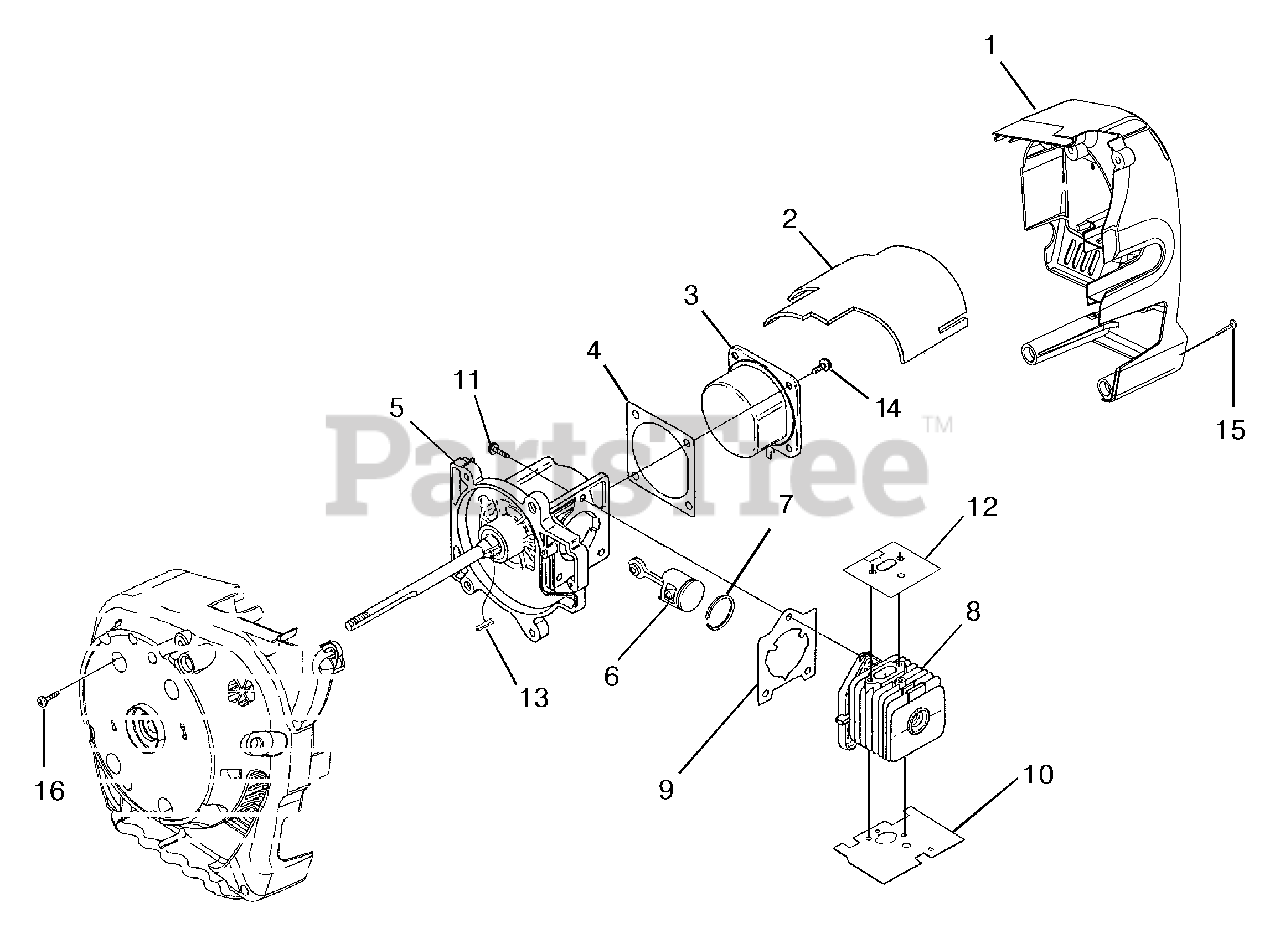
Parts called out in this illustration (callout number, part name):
1	Shroud
2	Heat Shield, Muffler
3	Crankcase Cover
4	Gasket, C/Case
5	Short Block (Svc)(30cc)
5	Short Block (Svc)(25cc)
6	Piston & Rod (30cc)
6	Piston & Rod (25cc)
7	Piston Ring (30cc)
7	Piston Ring (25cc)
8	Cylinder Kit (30cc)
8	Cylinder Kit (25cc)
9	Gasket, Cylinder
10	Gasket, Heat Dam
11	Screw, Sems (12-24 x 3/4)
12	Gasket, Muffler
13	Key, Woodruff
14	Screw, Sems (10-24 x .560)
15	Screw, Thread Forming (10-14 x 7/8)
16	Taptite, Truss (10-24 x 3/4)
